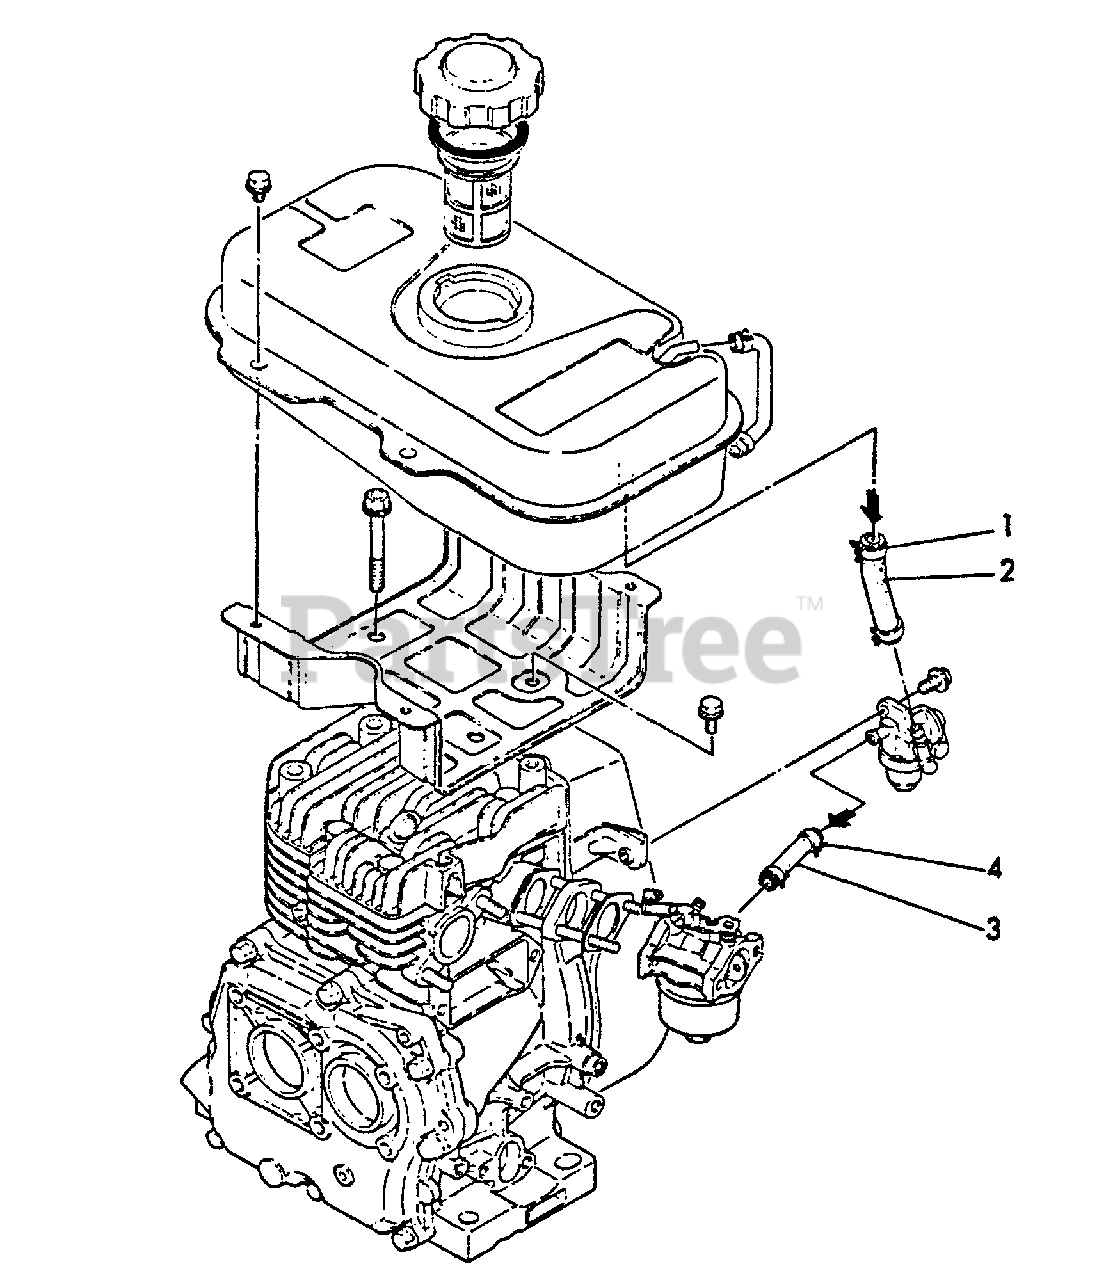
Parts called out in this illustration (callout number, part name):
1	CLAMP, HOSE
2	PIPE (A), FUEL
3	PIPE, FUEL
4	CLAMP, HOSE - 10
